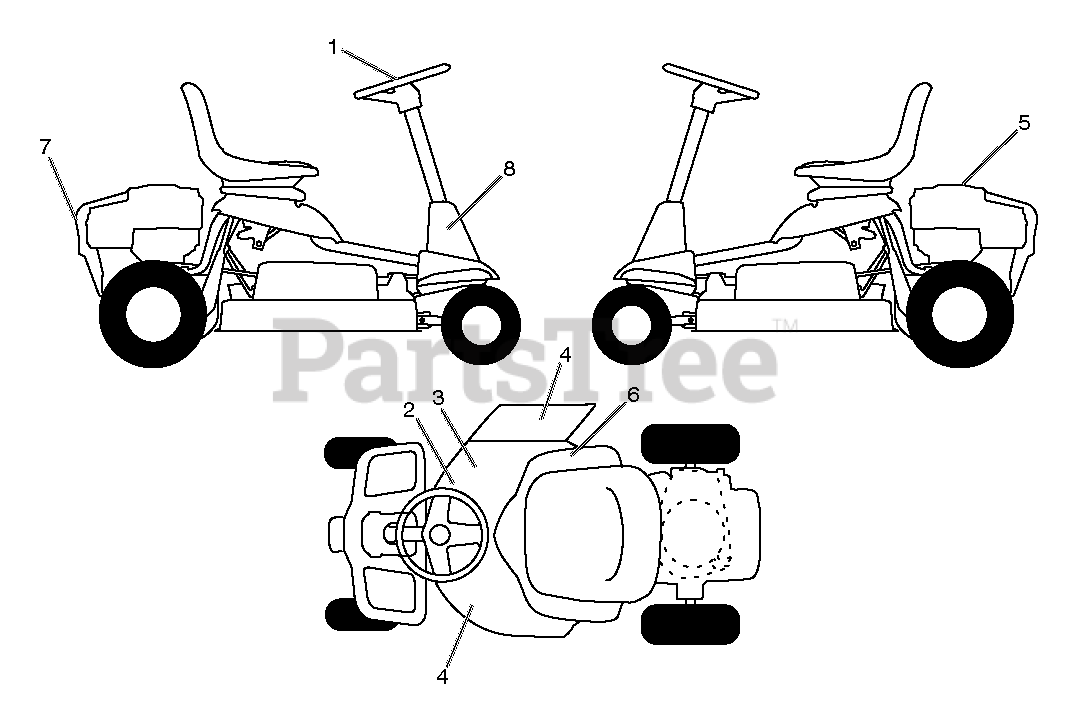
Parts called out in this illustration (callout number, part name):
1	Steering Wheel Decal
2	Decal, V-Belt Sch 30"
3	Decal, Warning Deflector Cut Finger
